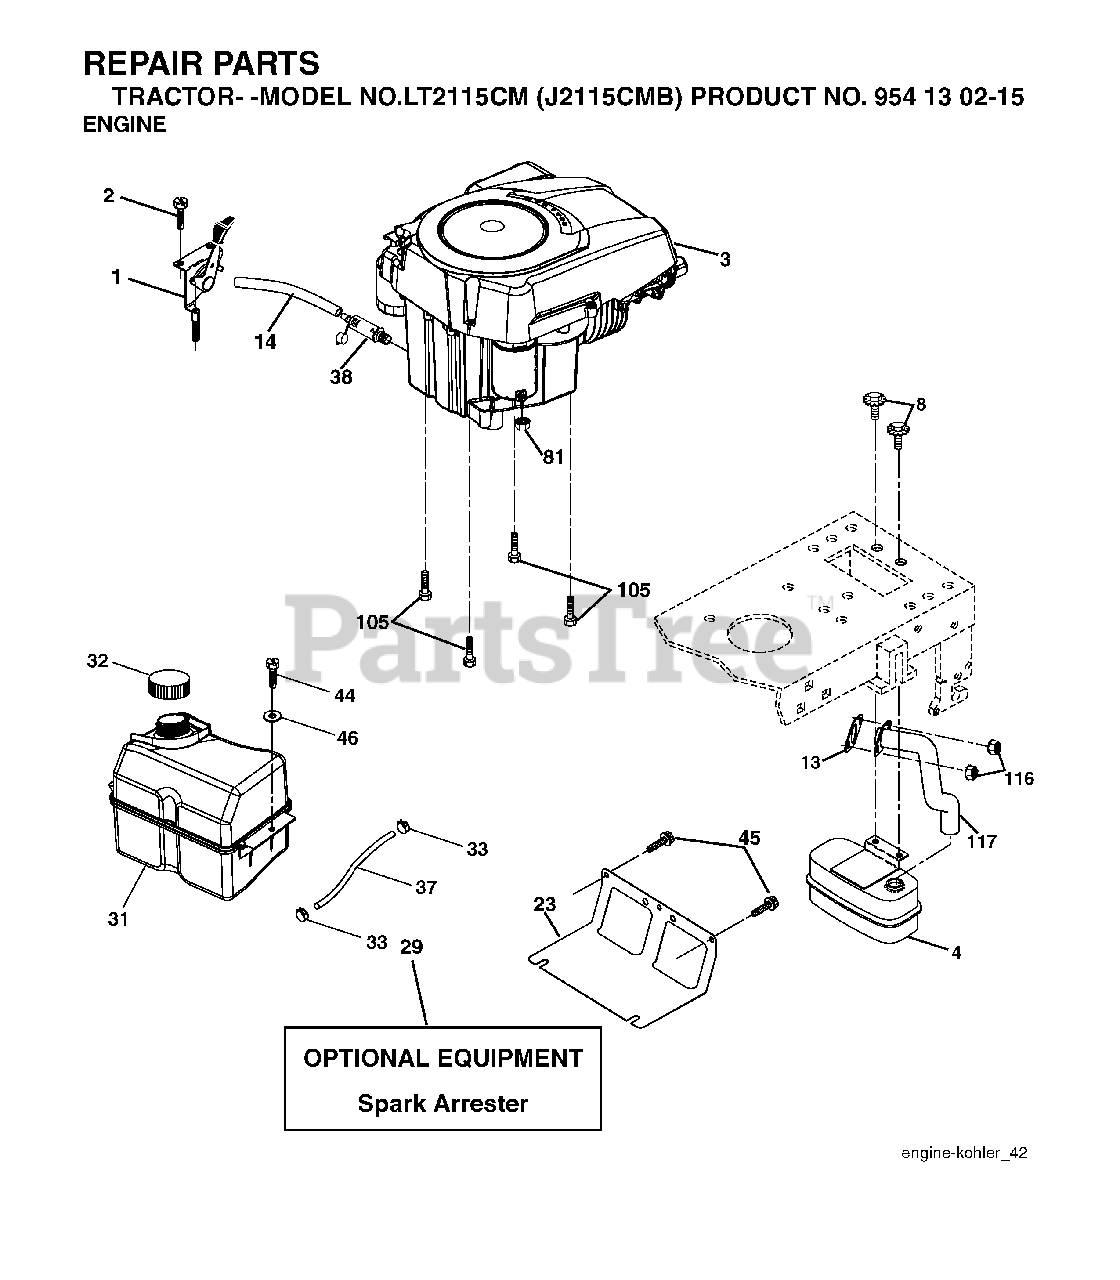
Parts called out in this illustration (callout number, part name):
1	CONTROL.THROTTLE.LT/YT
2	SCREW
4	MUFFLER.SINGLE.CYL.KOHL/B&S
8	BOLT, 5/16-18 X 1 3/4
13	GASKET ENGINE
14	TUBE, DRAIN OIL ASM.
23	SHEILD.BROWNING.DBR.GUARD
29	ARRESTER SPARK (OPTIONAL)
31	TANK FUEL
32	FUEL CAP
33	HOSE CLAMP
37	LINE.FUEL.20
38	PLUG DRAIN OIL EASY
44	SCREW HEXWSHR 1/4-20X3/4
45	SCREW, 3/8-16X3/4
81	NUT
105	SCREW 3/8-16X1
116	NUT.HEX.FLANGE.TOPLOCK
117	TUBE EXHAUST
